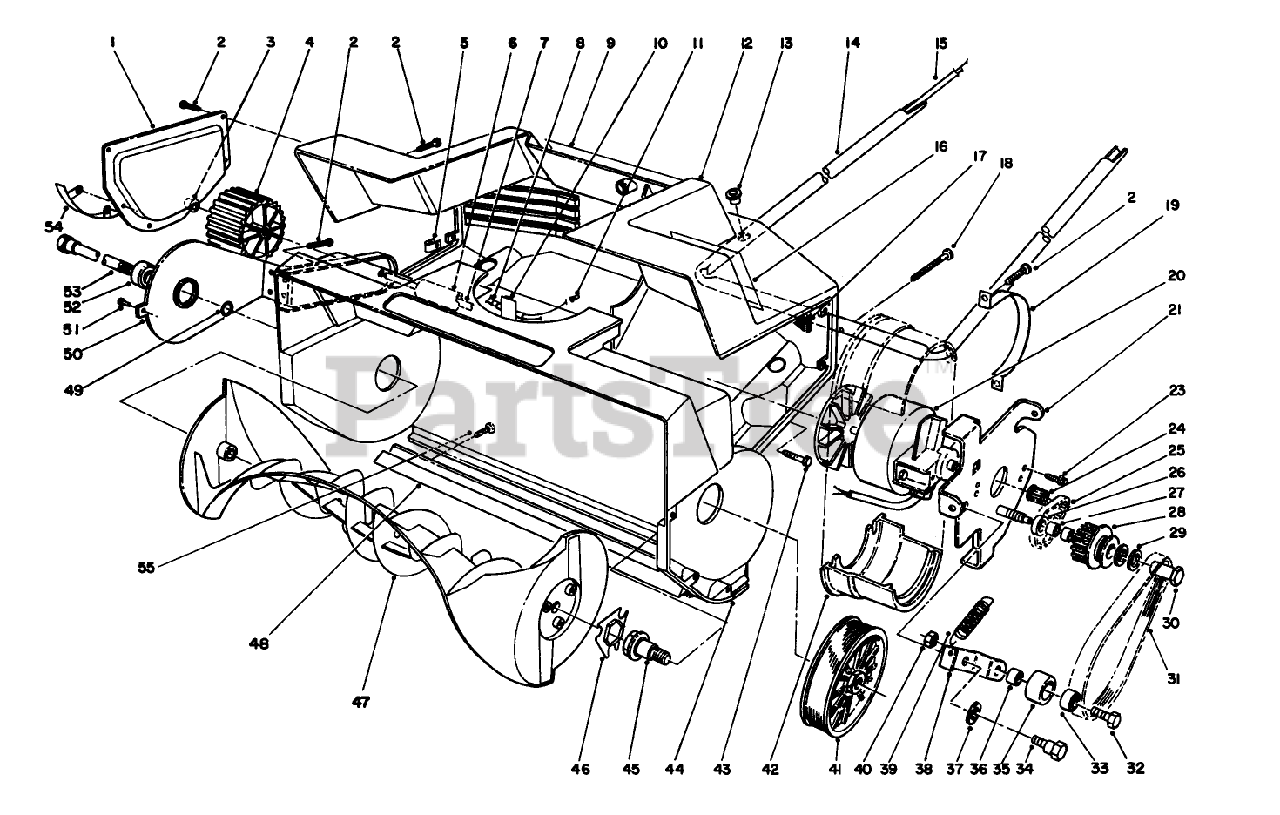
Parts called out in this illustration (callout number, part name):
1	PLATE - SIDE, PAINTED
3	PUSHNUT-CAP, WASHER
7	AXLE SHAFT
8	STRAIN RELIEF-GRIPMASTR
9	Decal-Danger Used on Machines Serial Nos. (1000101 Thru 1111100)
11	CONNECTOR SCREW
13	BUSHING
17	FOAM FILTER
18	SCREW-PLASTIC, PPH
19	STRAP-MOTOR, FINISHED
20	X-REF 99-5389
23	TEKS SCREW
25	BELT-PULLEY, IDLER/DRIVER
26	WASHER
27	DISC - ORD PULLEY
29	WASHER-THRUST
30	IDLER BOLT
32	SCREW-HH
34	SCREW-SHOULDER
35	Pulley
36	WASHER-IDLER
37	WASHER
38	IDLER BRACKET
39	IDLER SPRING
40	NUT-LOCK, NI
41	DRIVEN PULLEY
42	1800 CLAMP MTR BRCKT
43	SCREW-HWH THD CUT
45	SHAFT, ROTOR DRIVE
46	COUPLER, ROTOR
48	SCRAPER - 1800
49	WASHER-THRUST
50	WHEEL BRKT ASSY/1800
51	RIVET-POP
54	SKID, 1800
